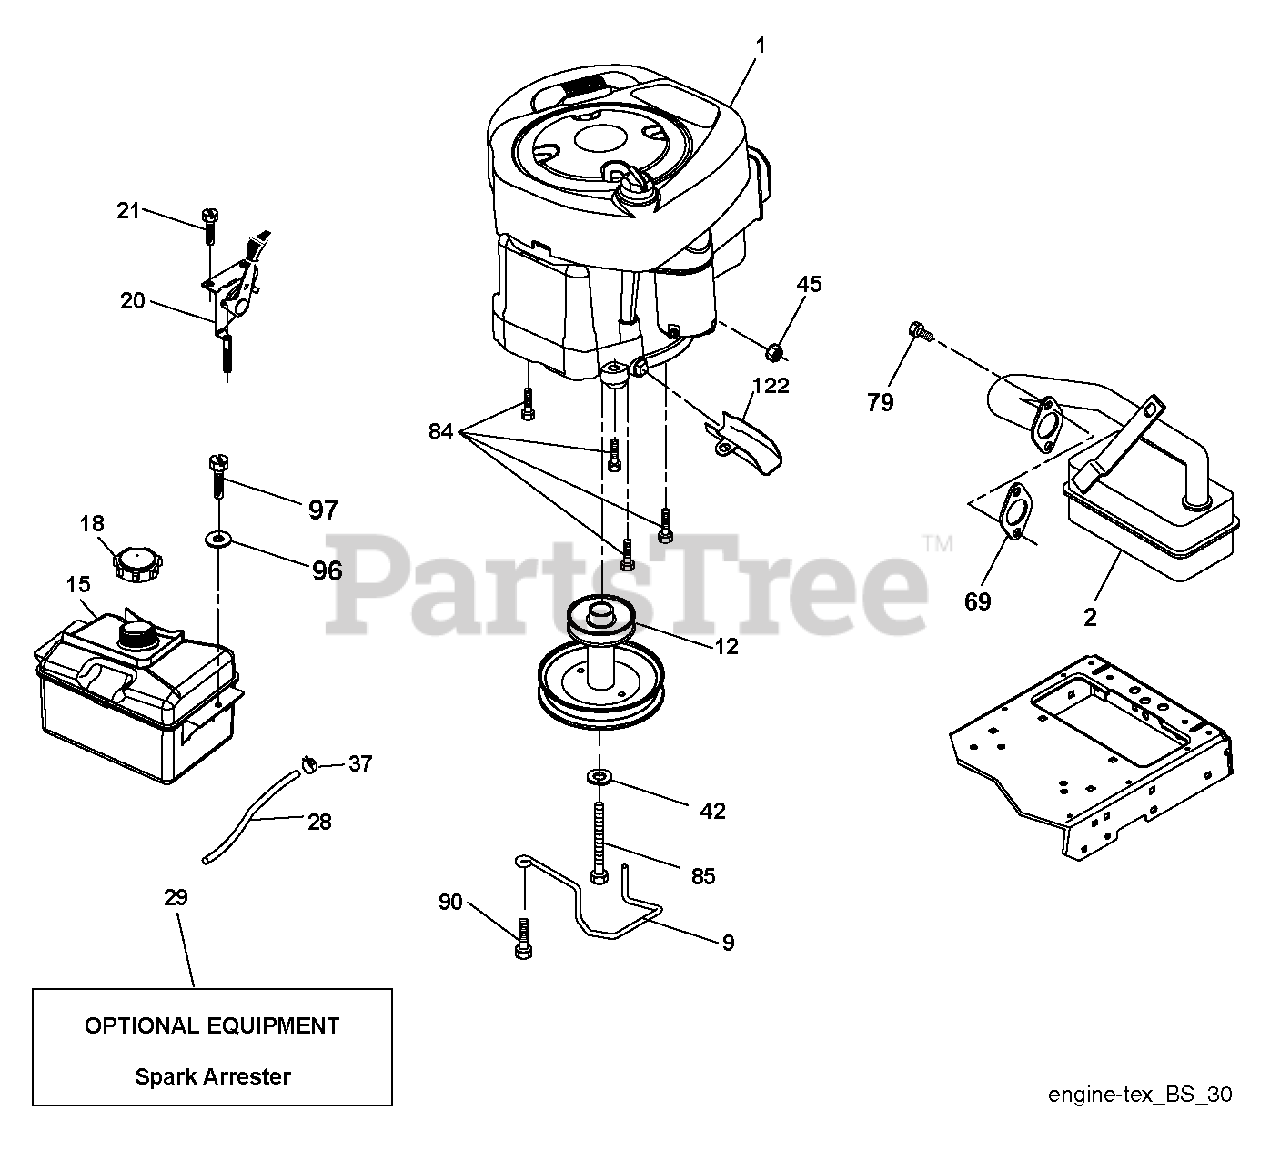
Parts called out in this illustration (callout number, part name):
2	MUFFLER.B&S.MODEL.21.11HP.OHV
9	KEEPER.BELT.ENGINE.3.25
12	PULLEY ENGINE
15	FUEL.TANK.ASM.1.5.GAL.NON-EPA
18	CAP ASM.FUEL.2.25"FR.
21	SCREW.#10 X 0.750.BOS (2 2)
28	LINE.FUEL.20"FRONT.EMI
29	KIT.SPARK ARRESTOR(392390 B&S)
37	HOSE CLAMP
42	LOCKWASHER
45	NUT
79	SCREW.SOCKET HD.5/16-1
84	SCREW.3/8-16
85	BOLT HEX 7/16-20X4-1/4"
90	SCREW 3/8-16X1
97	SCREW HEXWSHR 1/4-20X3/4
122	EXTENSION DRAIN OIL
